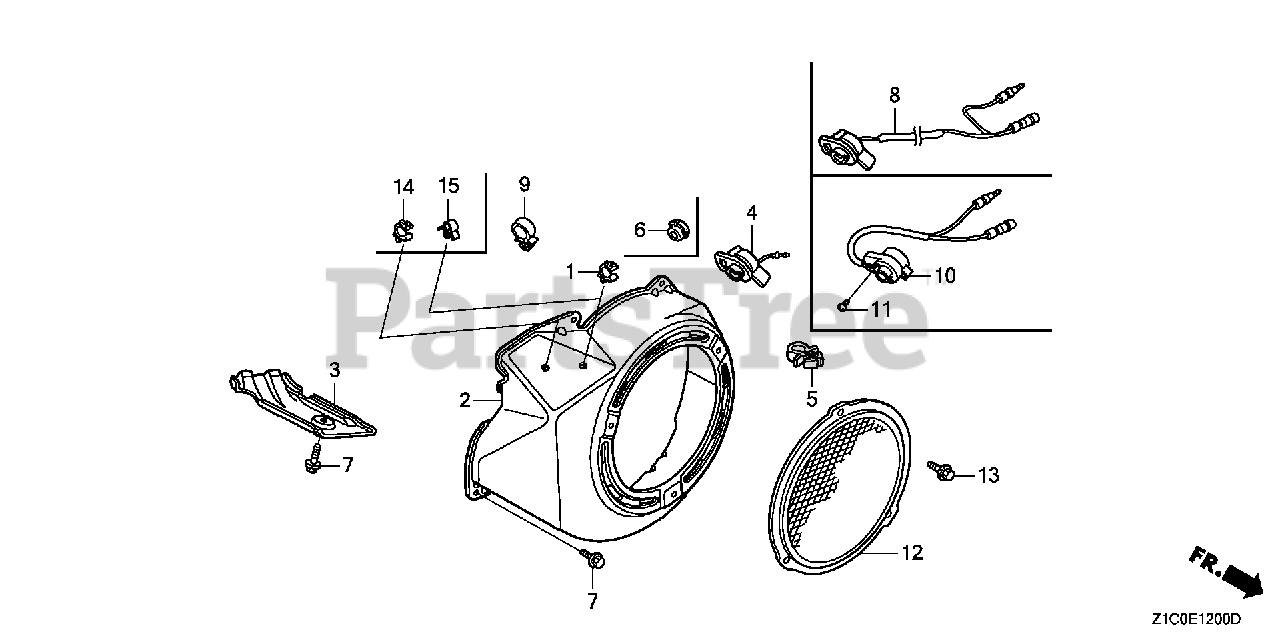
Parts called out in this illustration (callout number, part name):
1	CLIP, TUBE
2	COVER, FAN *NH1* (BLACK)
2	COVER, FAN *R280* (POWER RED)
7	BOLT, FLANGE (6X12) (CT200)
8	SWITCH ASSY., ENGINE STOP
